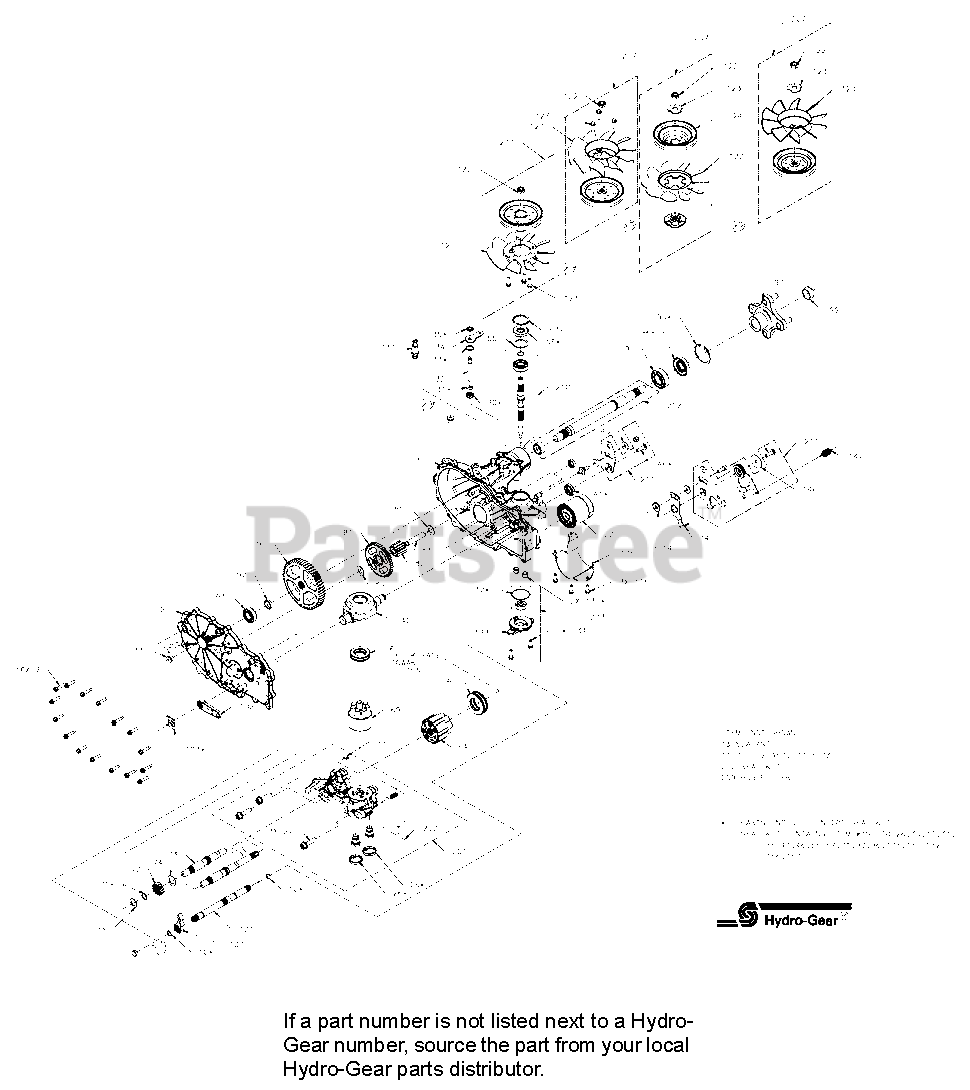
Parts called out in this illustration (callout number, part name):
1	KIT, HOUSING, MAIN, LH, CHRG, CNTL
2	KIT, COVER, SIDE, LH
7	HFHCS 1/4-20 x 1.125"
10	O-RING - 111 .103 x .424
11	PLUG 9/16-18 (METAL)
13	SEALANT
14	OIL, 20W50
22	PLATE, BYPASS
23	FILTER, OIL
26	SEAL, PLUG 1.250 x .250
27	HFHCS 3/8-16 x 1.5 (PATCH)
30	SEAL, LIP .375 x .75 x .25
31	RING, RET .375 EXTRNL
32	ROD, BYPASS
33	RING, RET .750 INTRNL
34	ARM, BYPASS
35	RING, RTNG .375 EXT
40	TRUNNION, SWASHPLATE
41	SEAL, LIP 12 x 32 x 7
45	WASHER .34 x .88 x .06
46	TWHCS 5/16-24 x 1.00 (PATCH)
55	WASHER 1.23 x 1.56 x .04
56	SEAL, LIP 17 x 40 x 7
57	RING, RETAINING
60	BEARING, THRUST
64	ASS'Y, CYLINDER BLOCK, 16cc
65	BRG, THRUST BALL 30 x 52 x 13
69	ASS'Y, BLOCK 7 PISTON
70	WASHER .63 x 1.0 x .05
71	RING, RETAINING_.625
72	GEAR, 16T
73	SHAFT, MOTOR
74	WASHER .72 x 1.16 x .04
80	WASHER .5 x 1.0 x .03
81	GEAR, 43T
82	GEAR, 11T
83	JACK SHAFT (PIN)
90	RING, RET 2.06 INT
91	GEAR, 54T
92	SPACER, .75 x 1.32 x .257
93	BEARING, BALL, .75 x 40 x 12
95	BRG, BALL 1.0 x 52 x 15 OPEN 6205M
96	SEAL, LIP 25 x 52 x 10 TC (GRAY)
97	KIT, HUB, 4 BOLT
99	NUT, HEX LOCK 3/4-16
100	PAWL, BRAKE
101	SHAFT, BRAKE
102	HANDLE, ACTUATING
103	CLIP, RETAINING
105	HFHCS 1/4-20 x .75
106	GUARD, FILTER, LH
111	FITTING, STR 9/16-18 SAE .5 BARB
120	FAN 7", 10 BLADE
122	NUT, HEX JAM 1/2-20 W/PATCH
123	HFHCS 1/4-20 x .875
130	TUBE, CONNECTING
131	GEROTOR ASSEMBLY (1.9 cc/rev)
132	O-RING, -137, 0.103 x 2.050
133	COVER, CHARGE PUMP
134	HFHCS 1/4-20 x .75
140	SPACER .320 x 1.005 x .179
141	ARM, NEUTRAL LEFT
142	SHCS 5/16-24 x 1 PATCH
146	WASHER, .343 x 1.500 x .062
147	SPRING, EXTNSN RTN-34-LBS
200	KIT, SEAL
201	KIT, CENTER SECTION, LH, CHRG
202	KIT, CHARGE RELIEF
203	KIT, CHARGE PUMP
207	KIT, FAN & PULLEY
209	HUB PULLER, 4 BOLT
210	KIT, INPUT SHAFT
211	KIT, RTN, CCW
212	KIT, SHAFT, AXLE
